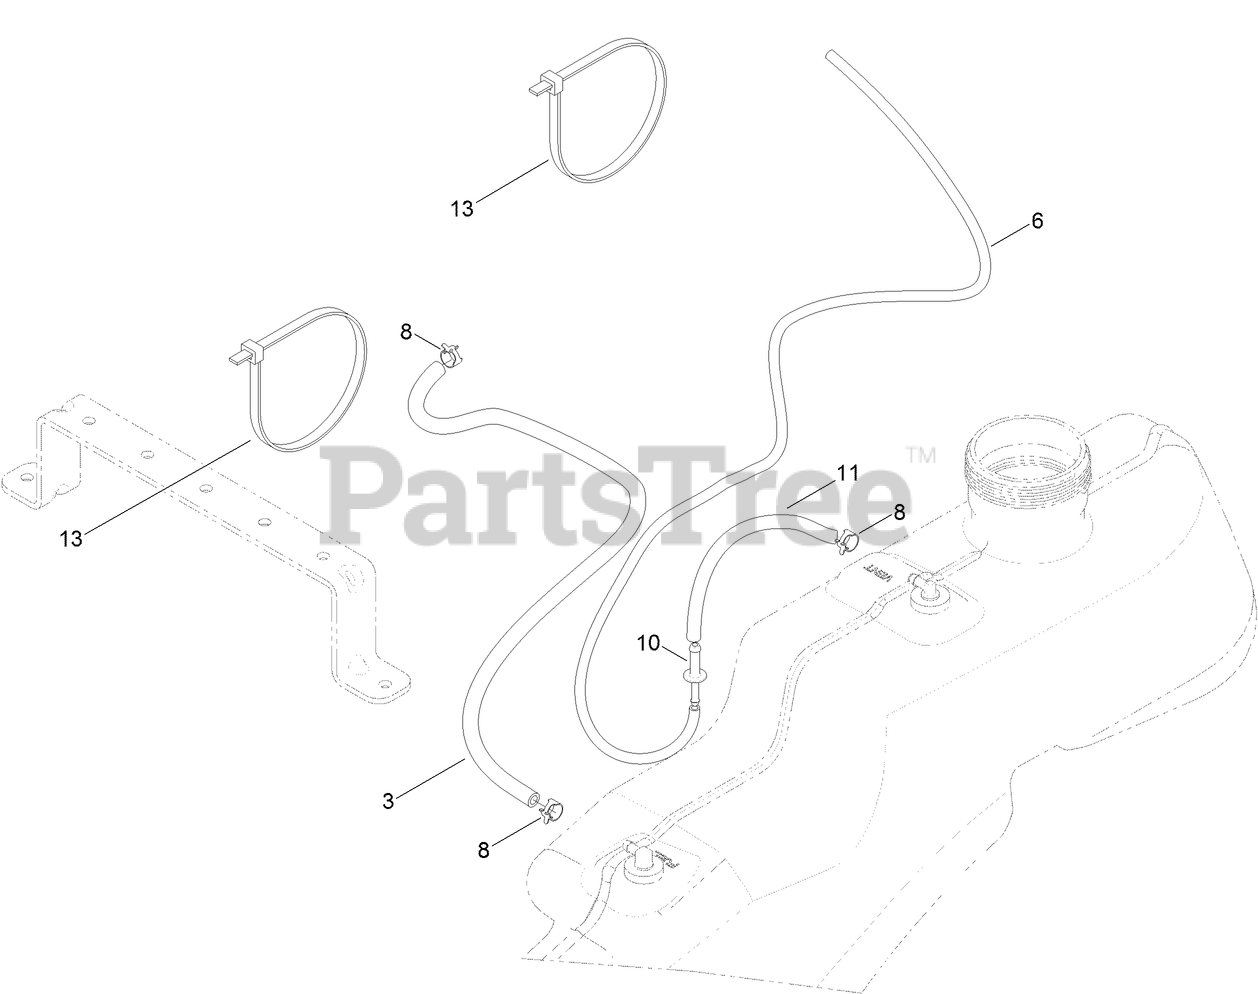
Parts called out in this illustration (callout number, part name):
3	HOSE-FUEL
6	HOSE-FUEL
8	CLAMP-HOSE
10	ADAPTOR-ORIFICE
11	HOSE-FUEL
13	TIE-CABLE
